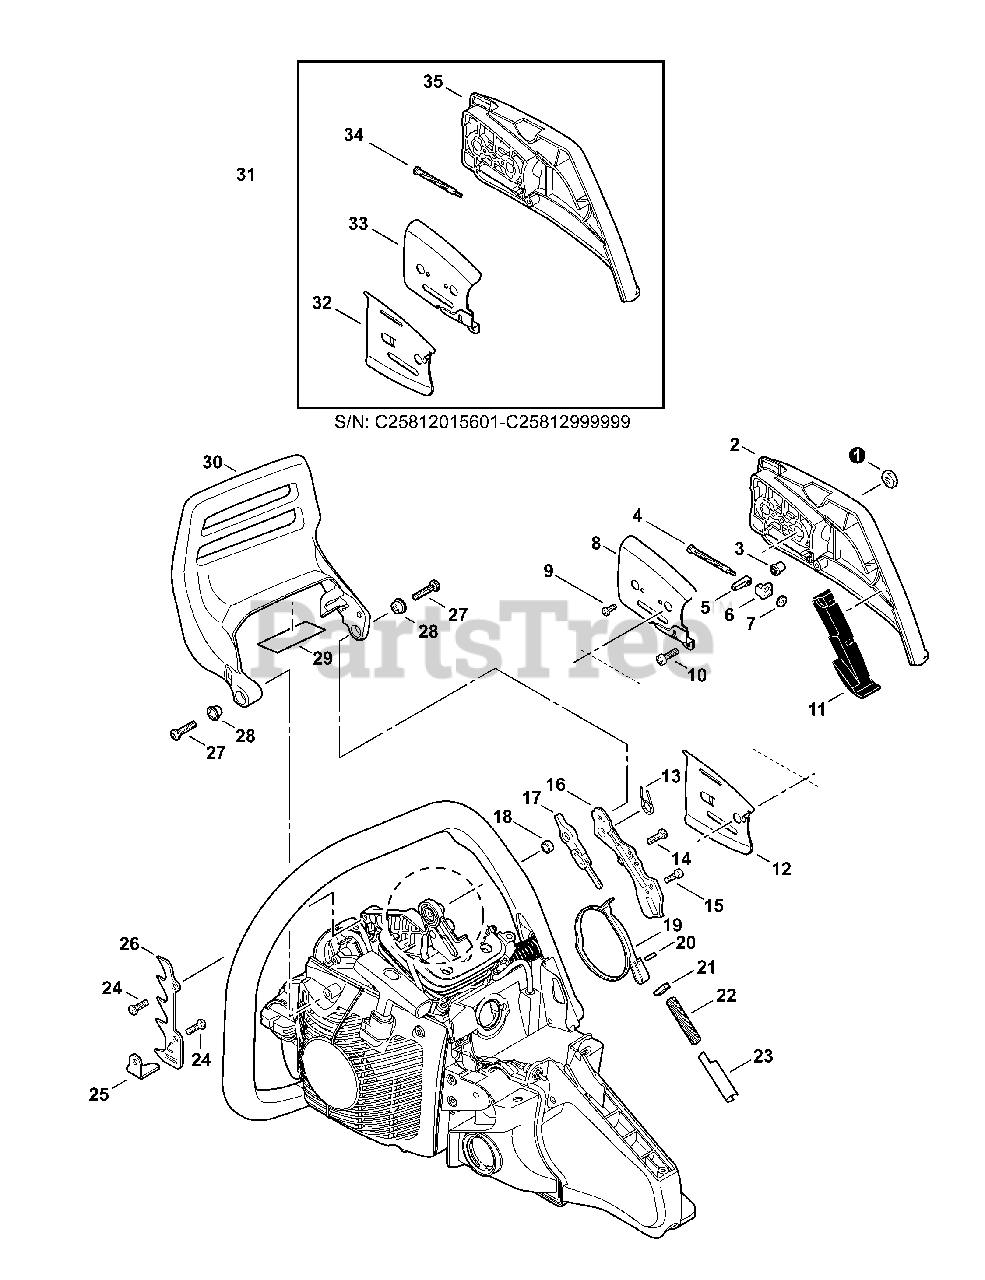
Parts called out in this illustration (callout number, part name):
1	NUT, FLANGE M8×1.25
2	GUARD, SPROCKET
3	GEAR, BEVEL
4	SCREW, CHAIN TENSION
5	TENSIONER, CHAIN
6	COLLAR 8
7	GEAR, BEVEL
8	PLATE, GUIDE - OUTER
9	SCREW 3×6
10	BOLT, TORX 4×12
11	CUSHION
12	PLATE, GUIDE - INNER
13	SPRING, TORSION
14	BOLT, TORX 5×16
15	BOLT, TORX 4×12
16	COVER, BRAKE
17	CONNECTOR, BRAKE
18	SPACER 12×10×T: 1.0
19	BAND, BRAKE
20	PIN, SPRING 3x-9.8
22	SPRING, COMPRESSION Ø12×70.5
23	PLATE, SIDE
24	BOLT, TORX 5×16
25	CHAIN CATCHER
26	SPIKE, BUMPER
27	BOLT, TORX 5×16
28	COLLAR 11.2×16.2×T0.6
29	SHIELD, HEAT 75×27×0.15
30	LEVER, BRAKE
31	GUARD KIT, SPROCKET
32	PLATE, GUIDE - INNER
33	PLATE, GUIDE - OUTER
34	SCREW, CHAIN TENSION 63 MM
35	GUARD, SPROCKET
